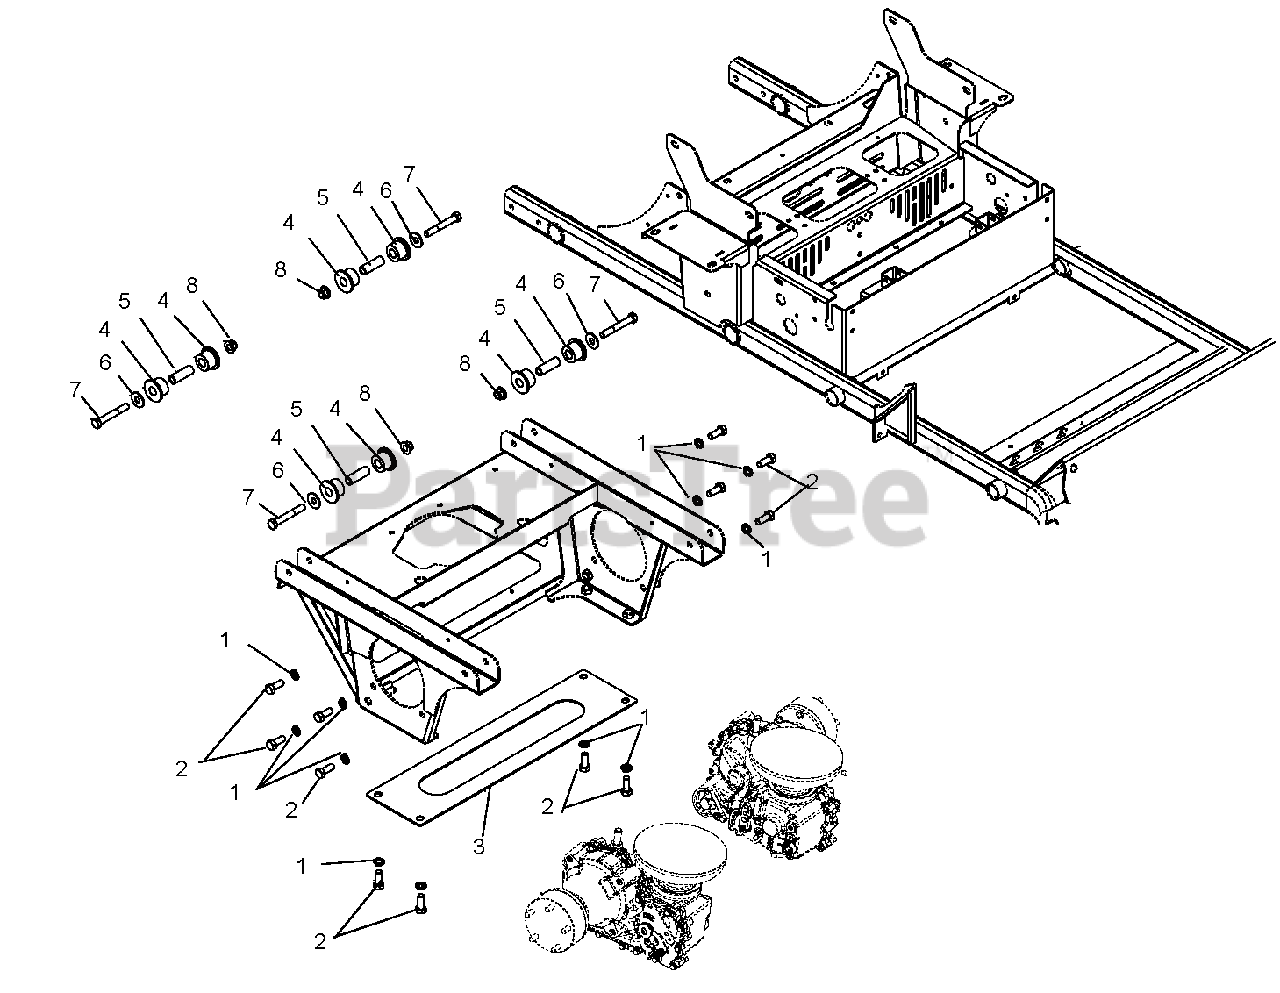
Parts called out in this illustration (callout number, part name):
1	Washer, Lock .50 x .125 REG YWZC
2	Bolt, Hex .50-13 x 1.25 GR5 YWZC
3	Plate, Transmission Connecting
4	Bushing, Flange .75 x 1.51 x 1.13 x 2.0 URE
5	Bushing, Sleave .50 x .75 x 2.23
6	Washer, Flat Steel.563 x 1.38 x .109YWZC
7	Bolt, Hex .50-13 x 3.50 GR5 YWZC
8	Nut, Locking Nylon-Flange .50-13 YWZC
